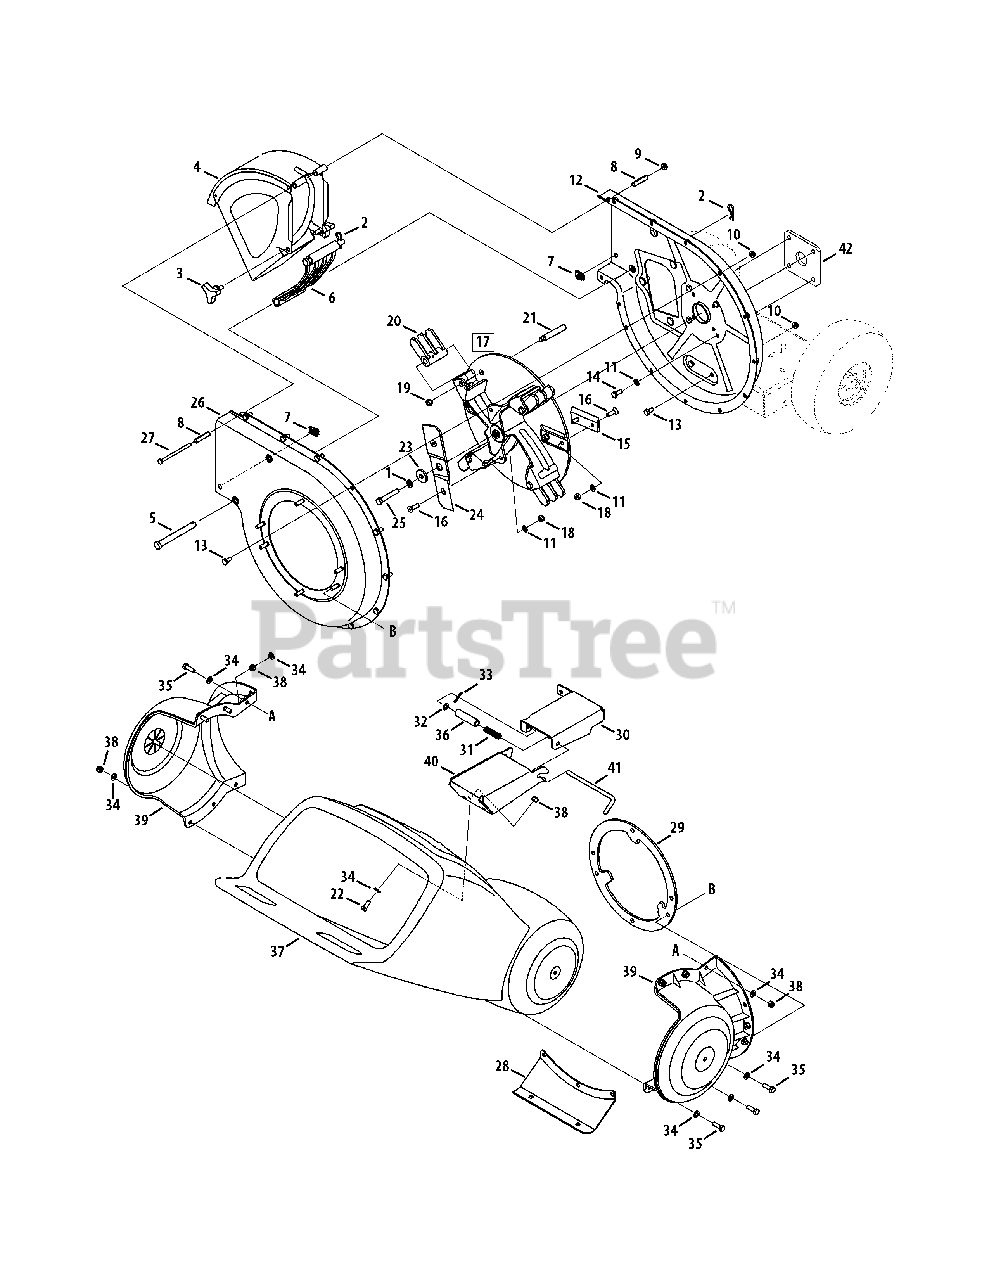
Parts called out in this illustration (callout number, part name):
1	Lock Washer, 3/8
2	Cotter Pin
3	Wing Knob 5/16-18
4	Chute Deflector Assembly
5	Clevis Pin
6	Shredder Screen
7	U-Nut 5/16-18
8	Spacer
9	Hex Lock Nut, 1/4-20
10	Hex Lock Nut 5/16-18
11	Lock Washer 5/16
12	Inner Impeller Housing Assembly
13	Hex Cap Screw 5/16-18 x .625
14	Hex Cap Screw 5/16-24 x 1.00
15	Chipper Blade
16	Hex Cap Screw 5/16-24 x 1.0
17	Impeller Assembly
18	Hex Lock Nut 5/16-24
19	Nut, Jam Lock, 3/8-16
20	Flail Blade
21	Shoulder Pin, .5 x 2.625
22	Hex Cap Screw 5/16-18 x .75
23	Flat Washer 3/8 x 1.25
24	Shredder Blade
25	Hex Cap Screw 3/8-24 x 2.25
26	Outer Impeller Housing Assembly
27	Hex Cap Screw 1/4-20 x 3.75
28	Front Support Bracket
29	Shredder Plate
30	Rear Hopper Bracket Assembly
31	Compression Spring 1.75
32	Flat Washer
33	Cotter Pin
34	Flat Washer .330 ID x. 630 OD
35	Hex Cap Screw 5/16-18 x 1.0
36	Spacer,.375 ID x 2.50 LG
37	Hopper Assembly
38	Hex Lock Nut 5/16-18
39	Hopper Collar
40	Front Hopper Bracket Assembly
41	Lock Rod
42	Engine Plate
